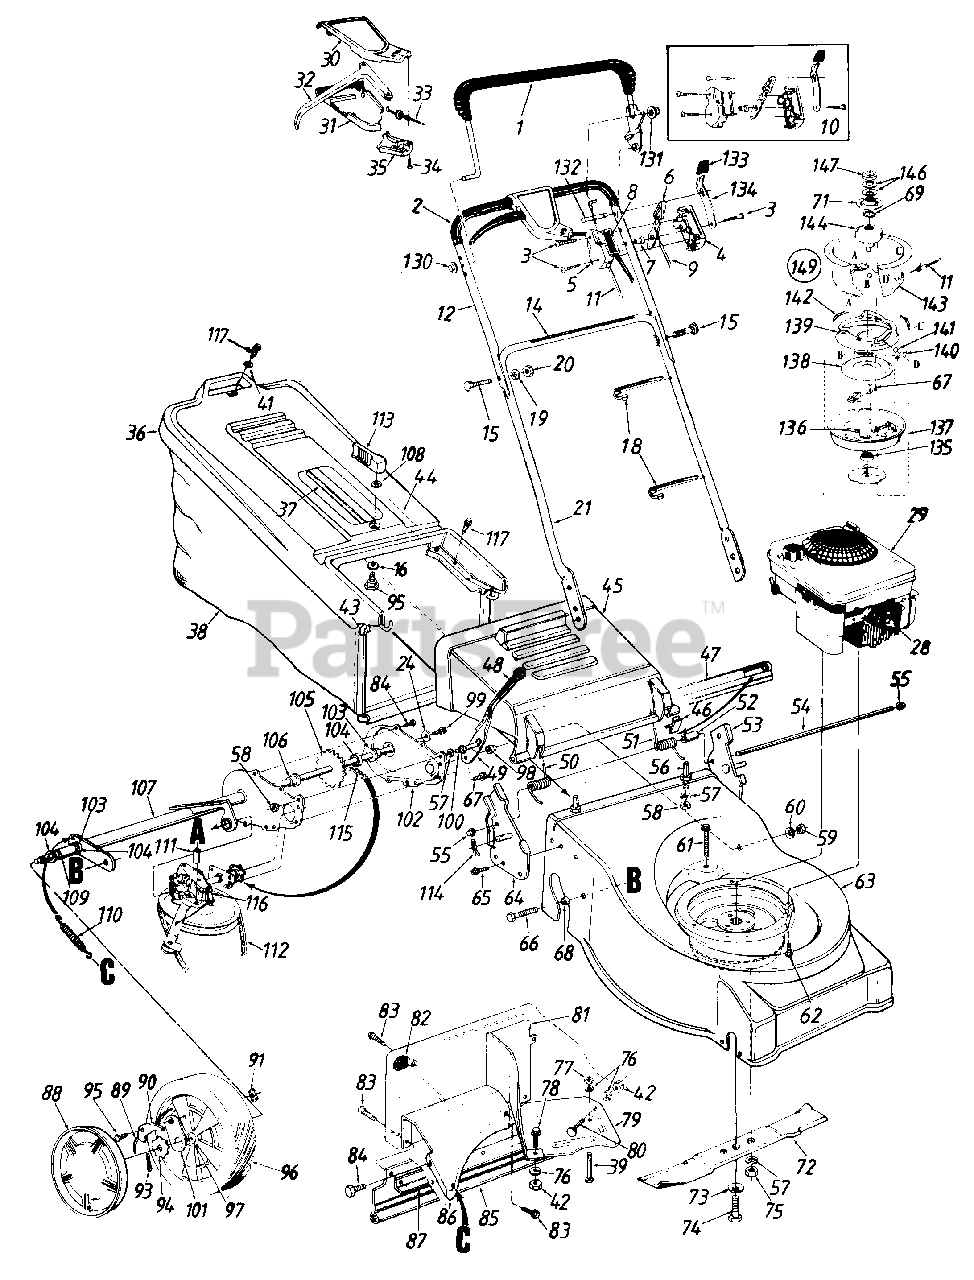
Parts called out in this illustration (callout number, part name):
1	Control Handle Ass'y.
2	Grip
3	Truss Mach. B-Tap Scr. #12 x 1.5" Lg.
4	Control Panel Half
5	Clutch Panel Half
6	Throttle Control Lever
7	Control Disc Pin
8	Control Label-Throttle
9	Throttle Wire-58" Lg.
10	Control Housing Comp.
11	Control Cable-52" Lg.
12	Upper Handle
14	Instruction Label-Handle
15	CuNed Carriage Bolt 5/16-18 x 1.38" Lg.
16	Bowed Washer
18	Cable Tie
19	L-Wash. 5/16" I.D.
20	Hex Nut 5/16-18 Thd.
21	Lower Handle
24	Bell-Wash. .265" I.D. x .75"
28	Spark Plug Boot
29	Engine
30	Control Cover Half-Upper
31	Control Cover Half-Lower
32	Control Lever
33	Drive Cable-53" Lg.
34	Flat C-Sunk Hd. Tap Scr. #10 x .75" Lg.
35	Cable Mtg. Cap
36	Hardtop Bag Cover
37	Hardtop Handle
38	Grass Bag
39	Truss Mach. Scr. 1/4-20 x 1.0" Lg.
41	Fl-Wash. .281" I.D. x .62"
42	Hex Nut 1/4-20 Thd.*
43	Front Catcher Frame
46	Deflector Plug
47	Seal-Extrusion
49	Spring Lever
50	Torsion Spring-R.H.
51	Torsion Spring-L.H.
52	Spacer .255" I.D.
53	Handle Brkt. Ass'y.-L.H.
54	Hinge Pin 17.75" Lg.
55	Cap Speed Nut
56	Shld. Pin 3/8-24 x 1.43" Lg.
57	L-Wash. 3/8" I.D.
58	Hex Jam Nut 3/8-24 Thd.
59	Hex L-Nut 3/8-24 Thd.
60	Bell-Wash. .38" I.D. x .88"
61	Hex Wash. Hd. Tap Scr. 1/4-20 x 1.5" Lg.
62	Hex L-Wash. Hd. Scr. 3/8-16 x l.O" Lg.
63	638/N 21" Deck Ass'y.
64	Handle Brkt. Ass'y.-R.H.
65	Hex L-Wash. Hd. AB-Tap Scr. 1/4 x.62" Lg.
66	Hex Wash. Hd. Tap Scr. 3/8-16 x .75" Lg.
67	Hex Wash. Hd. Tap Scr. 1/4-20 x .5" Lg.
68	Spacer.383" I.D.
69	Serrated Washer 1.0" I.D.
71	Serrated Pulley Half
72	21" Blade
73	Bell-Wash. .46" I.D. x .88"
74	Hex Bolt 7/16-20 x 2.0" Lg. (Gr. 5)
75	Hex Nut 3/8-24 Thd. (Gr. 8)
76	L-Wash. 1/4" I.D.*
77	Hex Jam Nut 1/4-20 Thd.
78	Hex Bolt 1/4-20 x .85" Lg.
79	Rear Belt Baffle
80	Carr. Bolt 1/4-20 x .50" Lg.
83	Torx Mach. AB-Tap Scr. 1/4 x .62" Lg.
84	Hex B-Tap Scr. 1/4 x .38" Lg.
85	Rear Flap
89	Plastic Spring
90	Pawl.345" I.D.
91	Weld Nut 1/4-20 Thd.
93	Cotter Pin 1/8" Dia.
94	Ratchet Wheel 1.62" O.D.
95	Shld. Bolt .342" Dia. x .268"
96	Wheel Ass'y. Comp.-Rear
97	Bearing 1/2" I.D.
98	Shld. Spacer .50" Dia.
99	Hex Bolt 1/4-20 x .62" Lg. (Gr. 5)
100	Shld. Pin 3/8-24 x 1.43" Lg.
101	Pawl Plate
104	Fl-Wash. .531" I.D. x .93"
105	Rear Axle Ass'y.
106	Hex Flange Bearing
109	Spacer.513" I.D.
110	Extension Spring 3.8" Lg.
111	Spacer.325" l.D.
112	V-Belt
113	Grass Catcher Locking Knob
114	Internal Cotter Pin 5/16" Dia.
115	#48 Chain 50" Pitch x 30 Links
116	Transmission Comp.
117	Hex L-Wash. Hd. AB-Tap Scr. 1/4 X .62" Lg.
132	Lock Pin .314" Dia. x l.75"
133	Spring Lever Knob
134	Lockout Spring
135	Ball Brg. .669" I.D. x 1.574"
136	Comp. Spring .35" O.D. x 2.0" Lg.
137	Clutch Blade Housing Ass'y.
138	Clutch Cone
139	Brake Cup Cone
141	Steel Ball 50" Dia.
142	Ext. Spring 1.75" Lg.
143	Clutch Housing
144	Fixed Pulley Adapter
146	Bell-Wash. 1.01" I.D.
147	Crankshaft Spacer
149	Blade Brake Clutch Ass'y. ComD
